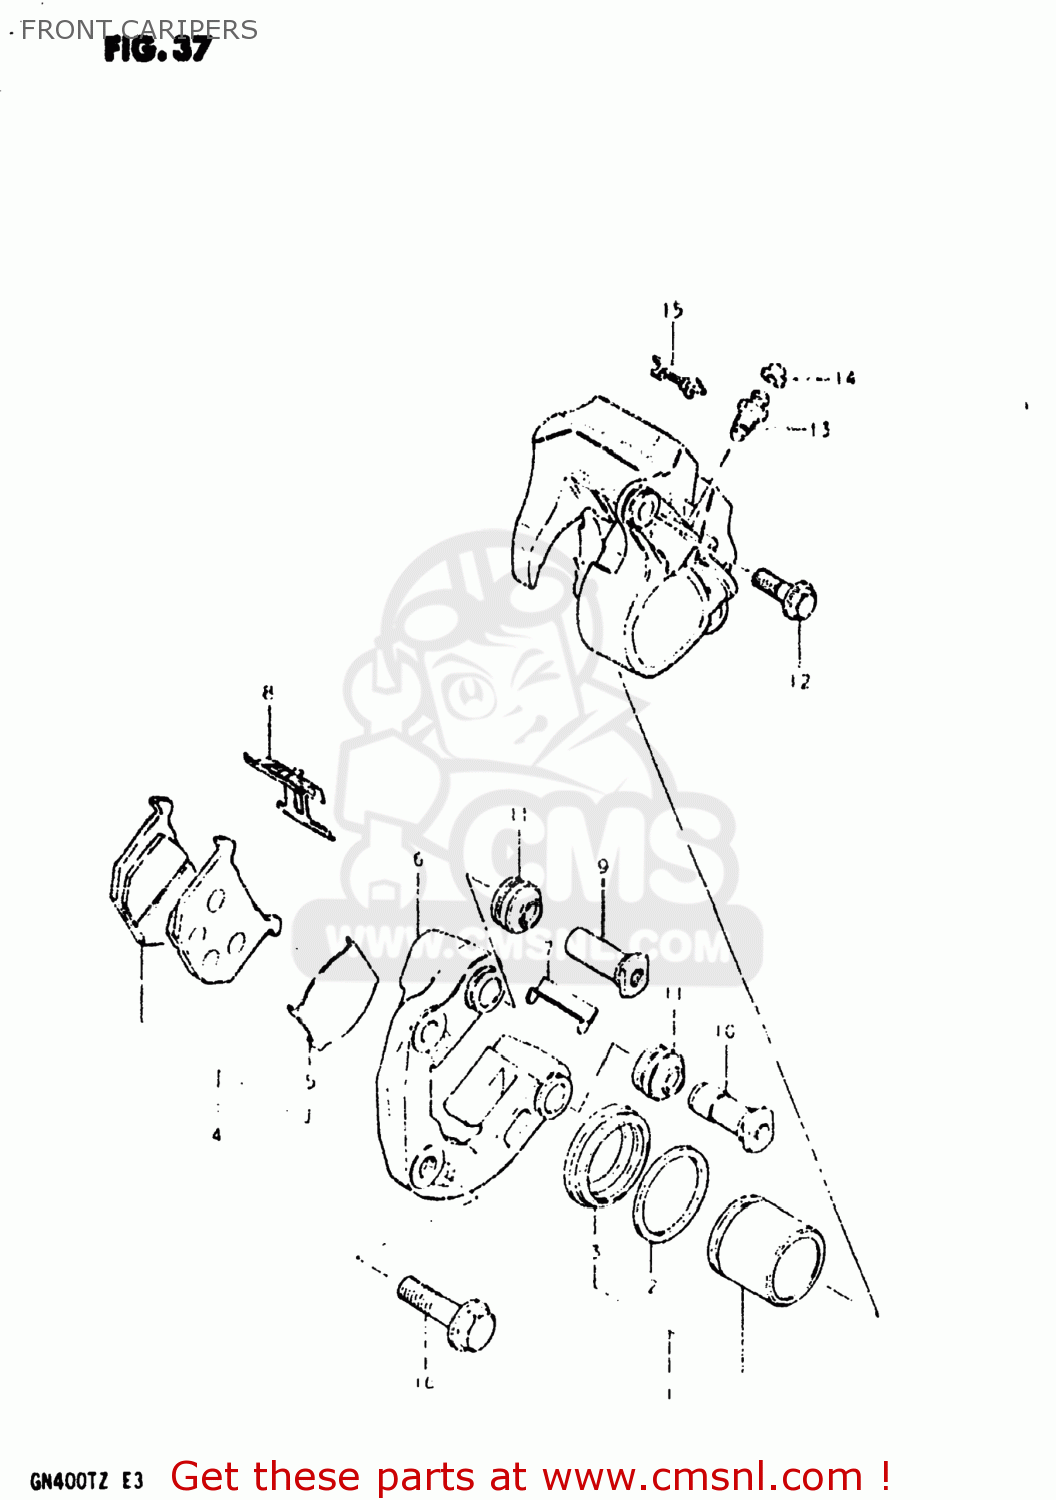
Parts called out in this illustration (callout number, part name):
1	PISTON SET
2	SEAL,PISTON
3	BOOT,PISTON
4	PAD SET (MCA)
5	SHIM,PAD
6	CARRIER,CALIPER,LEFT
7	GUIDE,PAD
8	SPRING,PAD
9	AXLE NO.1
10	AXLE NO.2
11	BOOT,AXLE
12	BOLT,CALIPER HOUSING
13	BLEEDER
14	CAP,BREATHER
15	COVER,INDICATOR
16	BOLT
